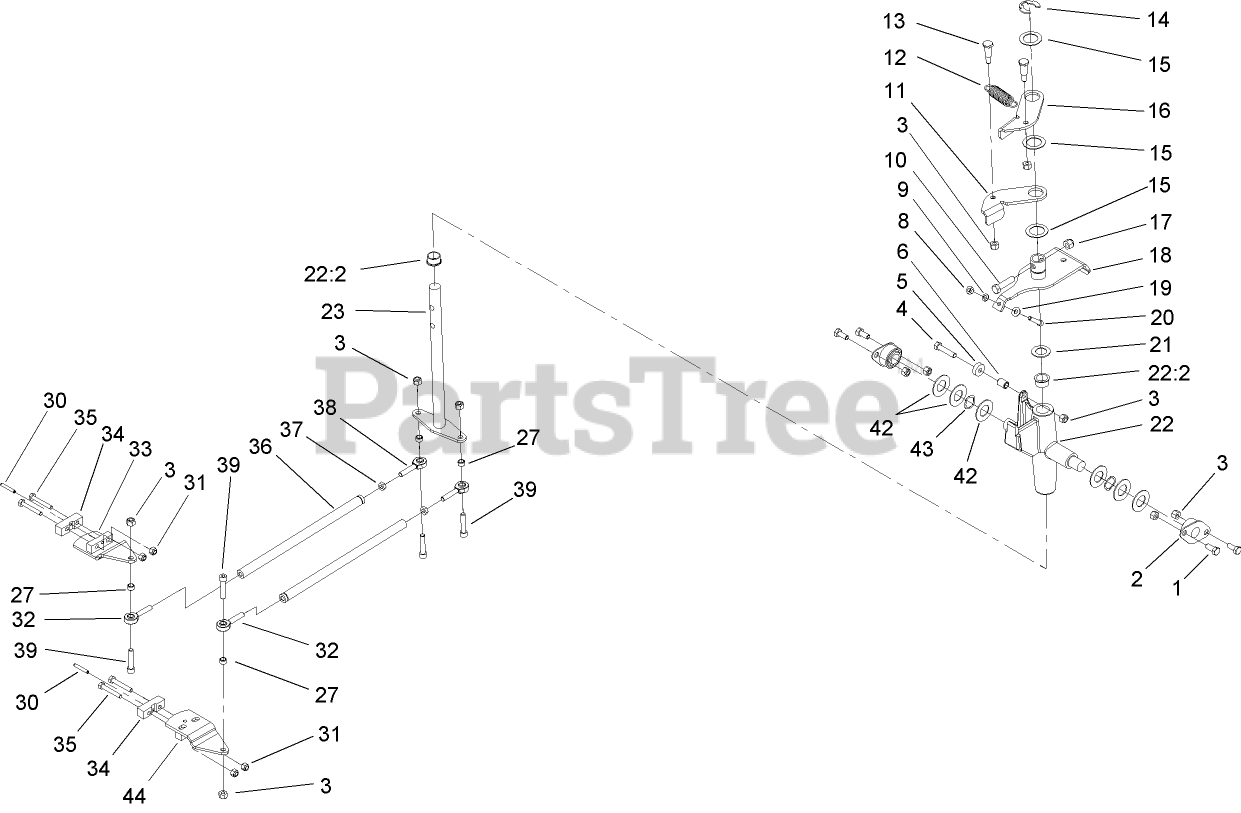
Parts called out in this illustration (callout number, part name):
1	SCREW-HH
2	BUSHING
3	NUT-LOCK, NI
4	SCREW-HH
5	BEARING-BALL
6	SPACER-LEVER, CONTROL
8	NUT-HEX
9	WASHER-LOCK
10	SCREW-HH
11	LEVER-RETURN, RH
12	SPRING-EXTENSION
13	SCREW-SHOULDER
14	RING-RETAINING
15	WASHER-PLAIN
16	LEVER-RETURN, LH
17	NUT-LOCK, NI
18	PIVOT LEVER ASM
19	WASHER-FLAT
20	SCREW-HSH
21	WASHER-THRUST
22	CONTROL SUPPORT ASM
22:2	BEARING-FLANGE
23	DRIVE ROD ASM
27	SPACER-LEVER, TRACTION
30	PIN-ROLL, SLOTTED
31	NUT-LOCK, NI
32	BEARING-ROD END, LH
33	PUMP LEVER ASM
34	CLAMP-TRACTION
35	SCREW-HH
36	ROD-LINKAGE
37	NUT-JAM
38	BEARING-ROD END, RH
39	SCREW-HSH
42	WASHER-FLAT
43	WASHER-SPRING, WAVE
44	PUMP LEVER ASM
